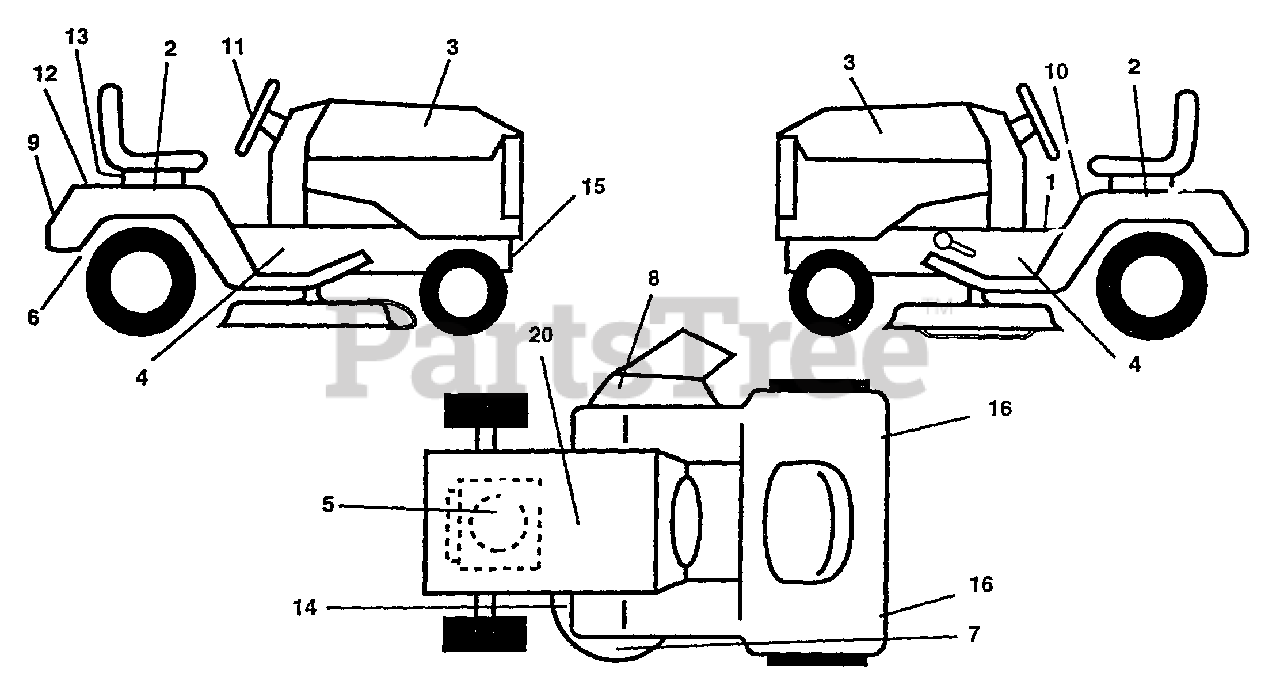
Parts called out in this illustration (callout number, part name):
1	Decal Oper Step Thru E/F
2	Decal Fender Auto Husq
3	Decal Hood LH
4	Decal Chassis 46"/20 HP
5	Decal HP Engine
6	Decal Drawbar Cntrl MVT Hyd LT
7	Decal Mower Enviro
8	Decal Warning Mult-Language
9	Decal Fender Logo
10	Decal Fender Danger E/F
11	Decal Ins Strg Whl
12	Decal Fender Predator
13	Decal Cust Assist Poulan Pro
14	Decal V-Belt Schematic
15	Decal Front Chassis
16	Reflector Tail Light
20	Decal Bat Dan/Psn
